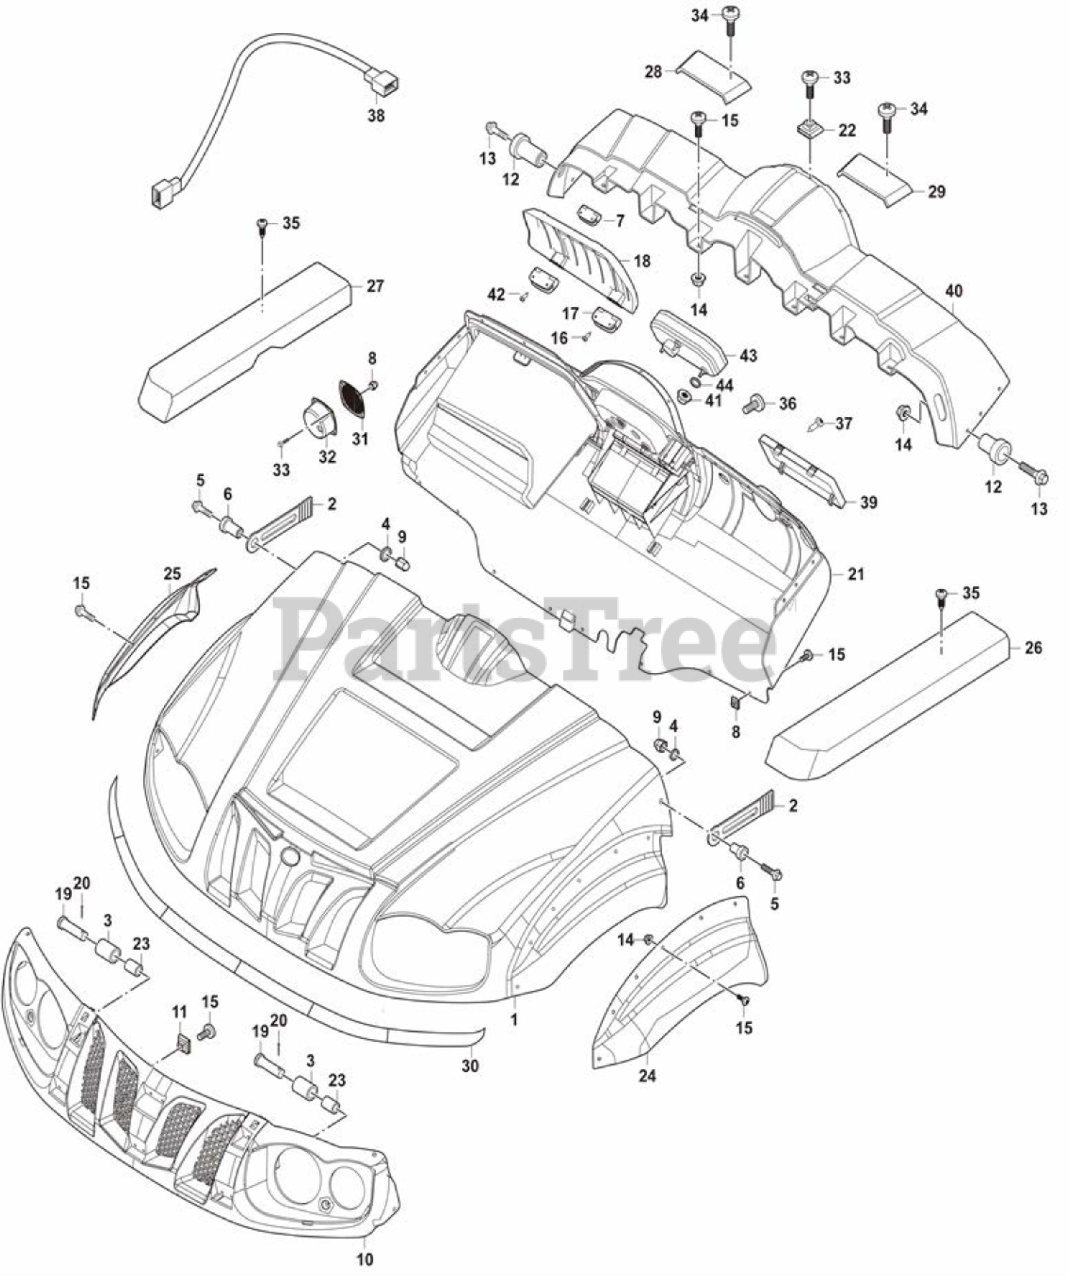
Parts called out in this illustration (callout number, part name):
1	Front board-Red
1	Front board-Blue
1	Front board-MTD Yellow
1	Front board-G2 Camo
2	Front Panel drawstring
3	Column Liner 13X25X30
4	Flat washer 6
5	Hexagon Flange Bolt M6X25
6	Turnup Liner 6X9X22X12
7	Sundry Box Locker
8	Hexagon Flange Self-Lock Nuts (With Metallic Insert) M6
9	Cap Nut M6x12
10	mounting plate ?headlight
11	Nut clamp M6X2
12	Drawstring Seat, front Panel
13	Hexagon Flange Bolt M6X35
14	Hexagon Flange Self-Lock Nuts (With Metallic Insert) M6
15	Cross Large Plate Head Screw M6X16
16	Cross Small Plate Head Tapping Screw ST3.9X13
17	Plastic Hinges ,Sundry Box
18	Sundry Box Cover
19	Step Cotter Pin 12.5X94
20	Cotter pin 2.5X30
22	Nut Clamp M6X6
24	Left Fender
25	Right Fender
27	Right Trim
28	Meter shield, trim strip I
29	Meter shield, trim strip II
30	Trim Strip III, Front Panel
31	Speaker Cover
32	Speaker Case
33	Hexagon Small Head Screw M6X20
34	Small Pan Head Tapping Screw With Cross Recess ST3.9X13
35	Small Pan Head Tapping Screw With Cross Recess ST3.9X13
36	Sunk Head Tapping Screw With Cross Recess ST6.0X20
37	Small Pan Head Tapping Screw With Cross Recess ST6.2X16
38	Connecting Cable, Speed Sensor
39	CD Case Cover
40	Meter shield-Red
40	Meter shield-Blue
40	Meter shield-MTD Yellow
40	Meter shield-G2 Camo
41	Hexagon Flange Nut M6
42	Meter Assy
43	Meter Assy
44	Flat washer 6
